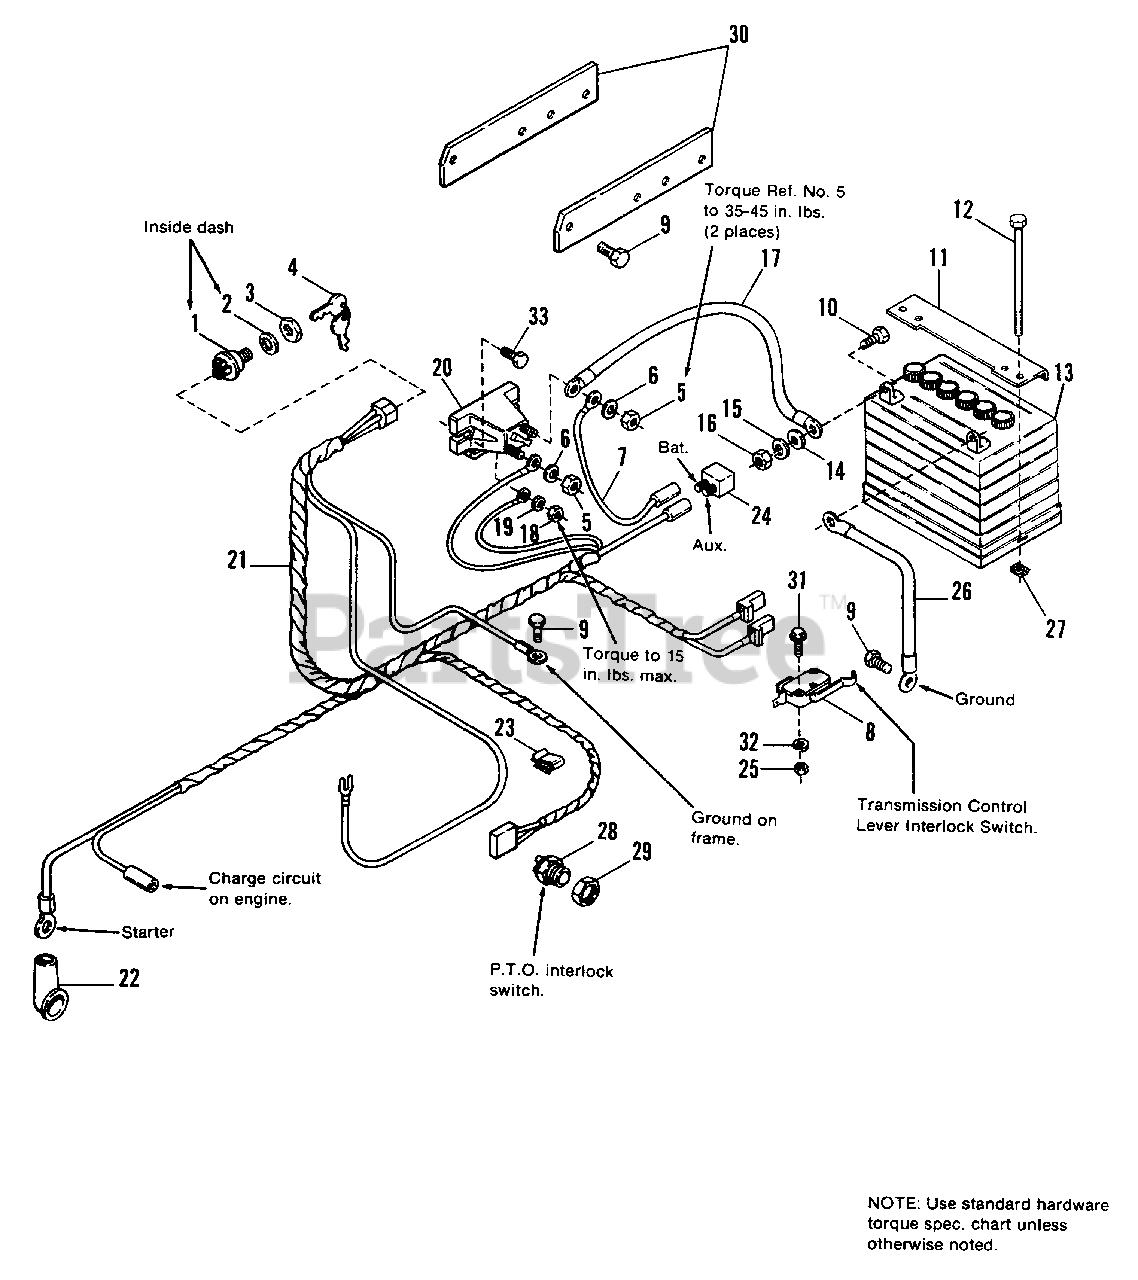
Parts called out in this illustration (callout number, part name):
1	SWITCH, Ignition (Incl. Ref. Nos. 1, 2, 3, & 4)
2	LOCKWASHER, Internal Tooth, 5/8
3	NUT, 5/8-32
4	KEYS, Set of 2
5	NUT, Hex, 5/16-18
6	LOCKWASHER, 5/16
8	SWITCH, Interlock
9	SCREW, Taptite, 1/4-20 x 3/8
10	CAPSCREW, Hex, 1/4-20 x 3/4
11	CLAMP, Battery
12	CAPSCREW, Hex, 1/4-20 x 7-1/2
13	BATTERY SERVICE KIT, 39 Amp.
14	WASHER, 1/4
15	LOCKWASHER, 1/4
16	NUT, Hex, 1/4-20
18	NUT, Hex, #10-32
19	LOCKWASHER, #10
20	SOLENOID
21	HARNESS, Wiring
22	COVER, Terminal
23	CLIP, Speed
24	CIRCUIT BREAKER
25	NUT, Hex, #5-40
27	NUT, Retainer, 1/4-20
28	SWITCH, Interlock
29	LOCKNUT, 9/16-18
30	BRACE, Shift Panel
31	SCREW, Rd. Hd., Phil. #5-40 x 3/4
32	LOCKWASHER, #5
33	SCREW, Taptite, 1/4-20 x 5/8
